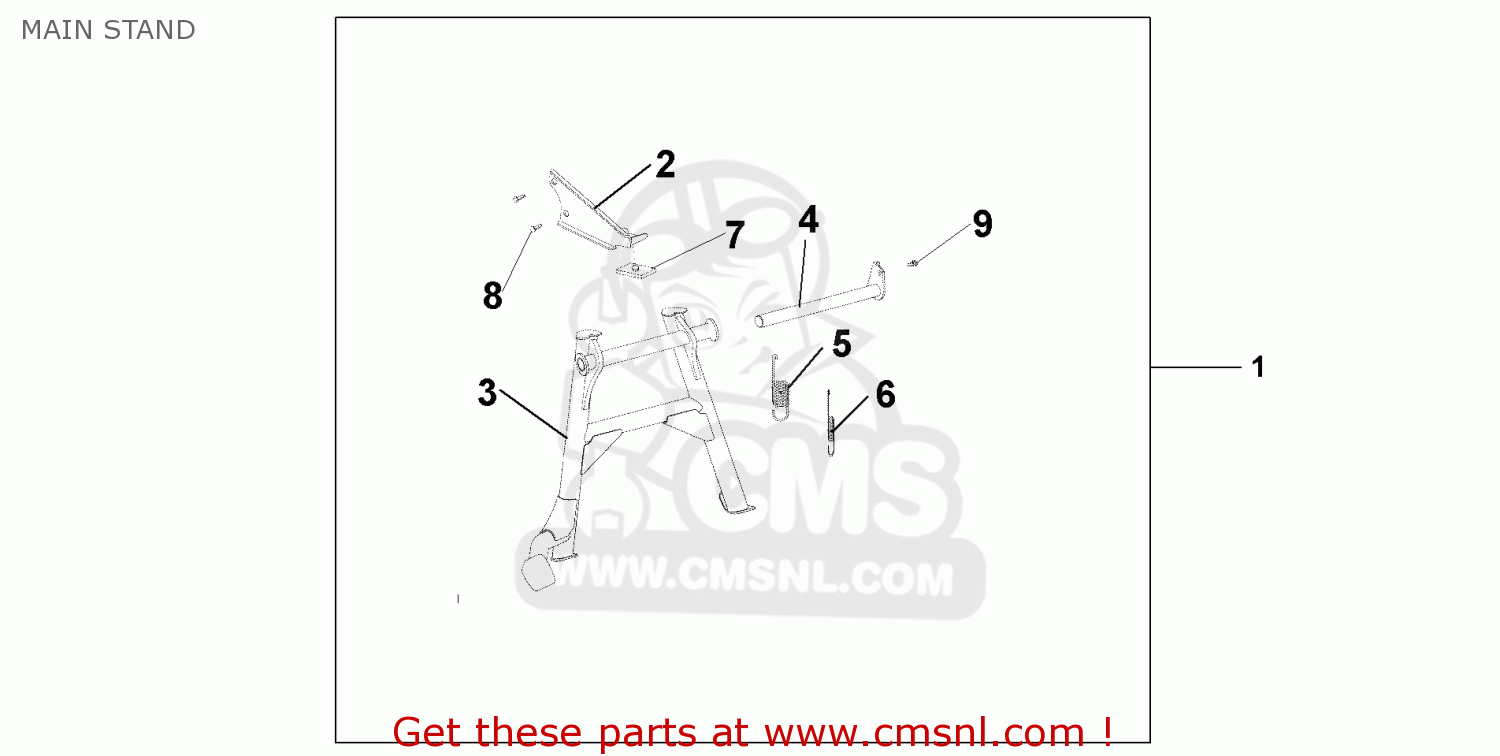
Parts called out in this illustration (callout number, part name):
1	MAIN STAND
2	STAND COMP. MAIN
3	STOPPER. MAIN STAND
4	PIPE. MAIN STAND SHAF
5	SPG ASSY,MAIN STA
6	SPG,MAIN STAND SU
7	RUBBER A,STAND
8	BOLT,FLANGE,8X14
